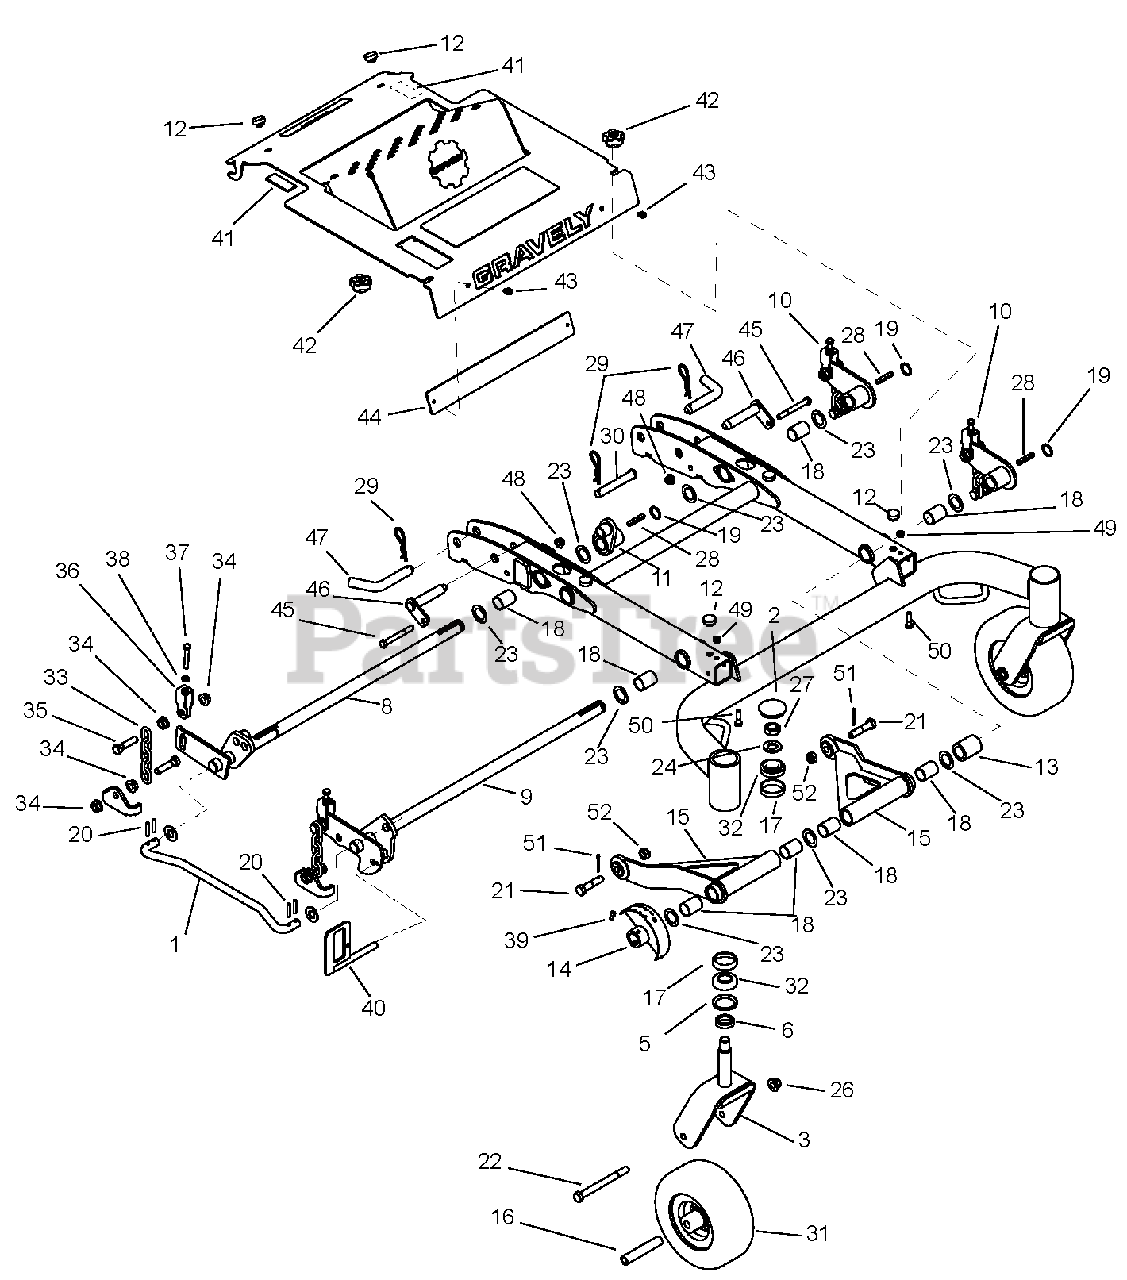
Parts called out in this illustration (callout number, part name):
1	Rod, Lift Assist 16.35
2	Cap, Dust
3	Weldment, Caster Fork (Outfront)
4	Weldment, Carrier Frame (Outfront)
5	Bearing, Seal 1.5 x 2 x .18
6	Spacer, 1.005 x 1.5075 x .375
7	Weldment, Carrier Foot Plate
8	Weldment, Shaft, Deck Lift
9	Weldment, Shaft, Deck Lift
10	Weldment, Lift Arm
11	Weldment, Mower Lift To Cylinder Arm
12	Bumper, Rubber Snap In
13	Spacer, 1.0 ID x 1.5 OD x 1.81 Lining
14	Cut Indicator Red
15	Weldment, Mower Mounting Arm
16	Bearing, .532 x .750 x 4.06
17	Bearing, Cup 1.980 x .420
18	Bushing, 1.00 ID x 1.125 OD x 1.50 LG
19	Ring, Retaining-External 1.00 x .078
20	Pin, Roll .250 x 1.25 Stainless Steel
21	Bolt, Hex .50-13 x 2.00
22	Bolt, Hex .50-13 x 5.50
23	Washer, Hardened-Thrust 1.00 x 1.55 x .03
24	Washer, Flat Steel .812 x 1.50 x .135 YWZC
25	Washer, Flat Steel .656 x 1.31 x .095 YWZ
26	Nut, .50-13 Nyloc Flange
27	Nut, Jam Center-Lock .75-16
28	Key, Straight .25 x 1.75 x .25
29	Pin, Hair-Internal .15 x 2.937
30	Pin, Clevis .625 x 4.0
31	Wheel Assembly 9.00 x 3.50
32	Bearing, Cone with Grease
33	Chain, Link
34	Nut, Spinlock Flange M12-1.75
35	Bolt, Hex M12-1.75 x .50 Class 8.8
36	Bracket, Deck Leveling
37	Bolt, Hex .312-18 x 2.00 FTH
38	Nut, Jam .312-18
39	Screw, Set .25-20 x .50 YZ EP 80
40	Pin, Deck Tilt (shipped loose in literature package)
41	Tape, Foam .12 x 1.0 x 2.50
42	Knob, Clamping .312-18
43	Screw, Tapping Hex Washer HD .25-20-.50
44	Plate, Bumper
45	Bolt, Hex .38-16 x 3.25
46	Weldment, Carrier Frame Mounting Pin
47	Pin, Bent .75 Dia.
48	Nut, Nyloc Flange .318-16
49	Nut, Locking-Center .31-18
50	Bolt, Hex .31-18 x 1.25
51	Pin, Cotter
52	Nut, .50-13
